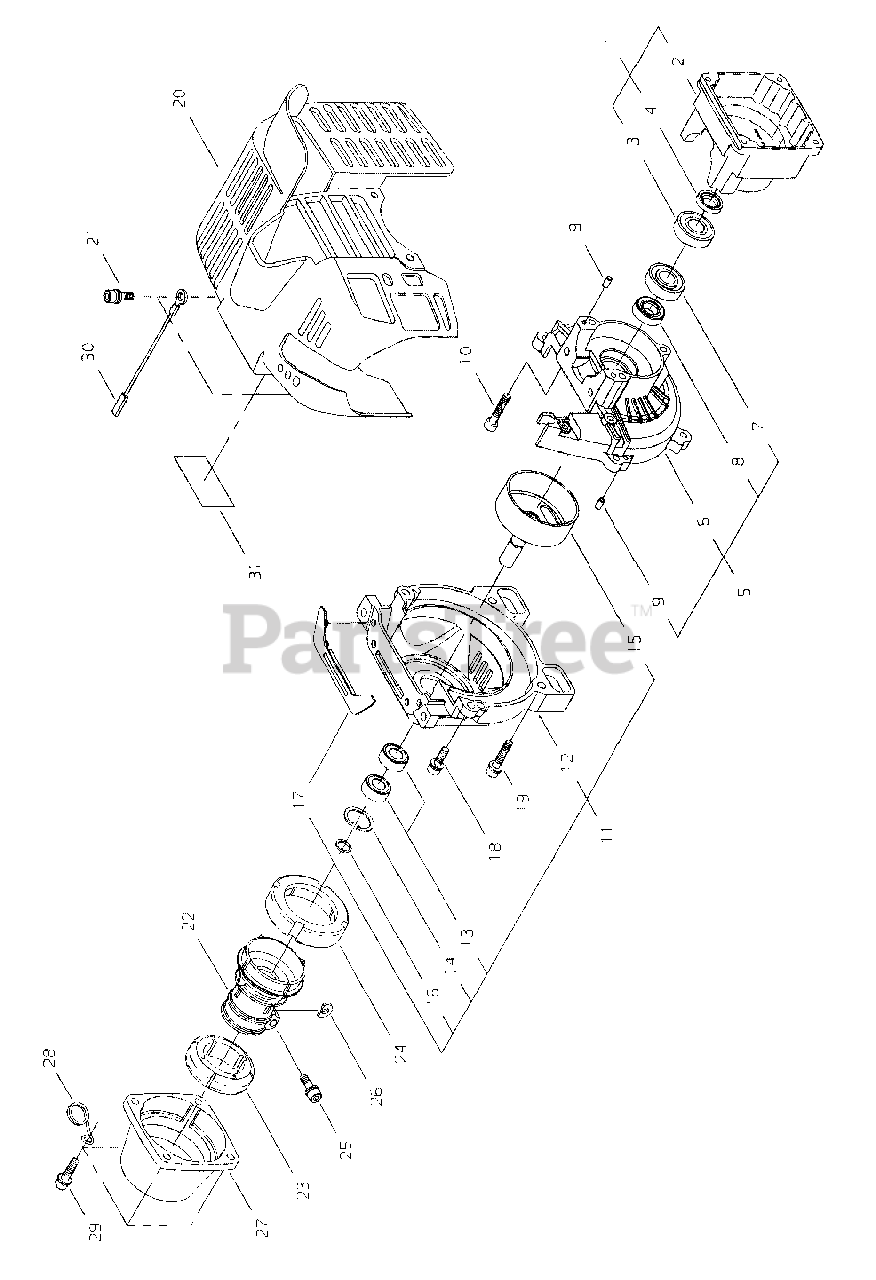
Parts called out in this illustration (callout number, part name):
1	CRANKCASE ASSY - REAR
2	CRANKCASE - REAR
3	BEARING, BALL 6001 C3
4	SEAL, OIL - 12
5	CRANKCASE ASSY - FRONT
6	CRANKCASE - FRONT
7	BEARING, BALL 6001 C3
8	SEAL, OIL - 12
9	PIN - LOCATING
10	SCREW - 5X25
11	COVER, FAN - RED
12	COVER, FAN - RED
13	BEARING, BALL - 6000
14	RING, RETAINING - 26
15	DRUM, CLUTCH
16	RING, RETAINING
17	CUSHION
18	SCREW - 5X16
19	SCREW - 5X30
20	COVER, ENGINE - RED
21	SCREW - 5X16
22	CLAMP, MAIN PIPE
23	CUSHION - FRONT
24	HOLDER, REAR CUSHION
25	SCREW - 5X25
26	SHIM
27	COVER, AV CUSHION (RED)
28	HOLDER, THROTTLE CABLE
29	SCREW - 5X20
30	LEAD - GROUND
31	LABEL - TRADE
